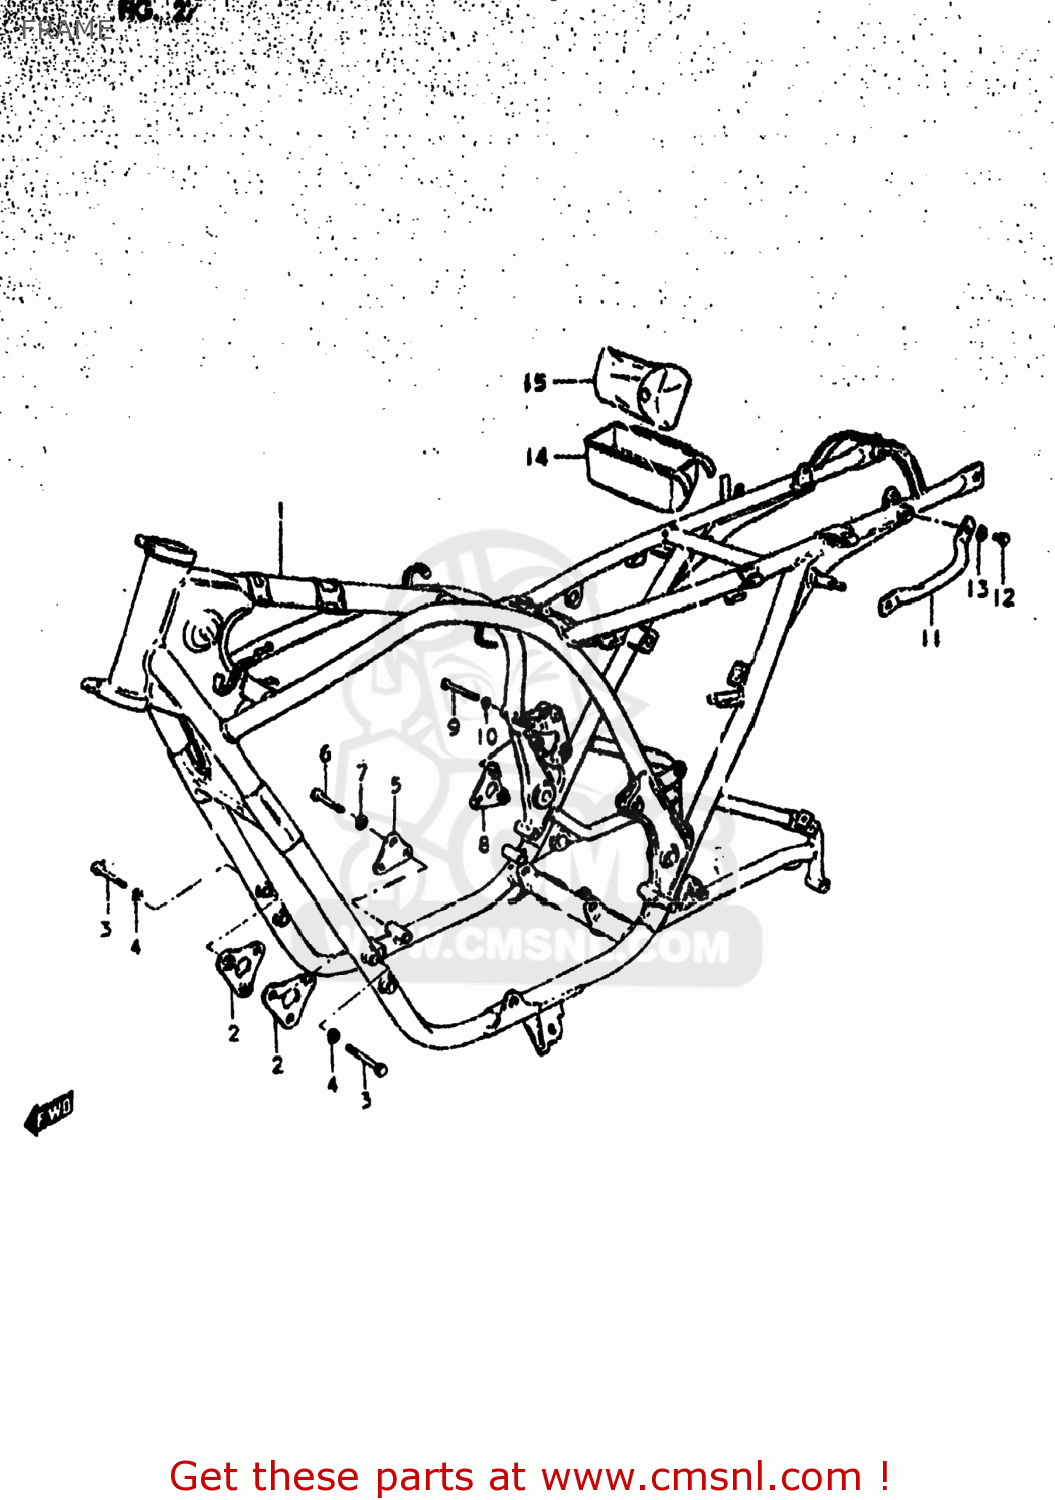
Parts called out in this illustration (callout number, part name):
1	FRAME
2	PLATE,ENGINE MOUNTING
3	BOLT
4	LOCK WASHER
5	PLATE,ENGINE MOUNTING
6	BOLT
7	LOCK WASHER
8	PLATE,ENGINE MOUNTING
9	BOLT 8X55
10	LOCK WASHER
11	GRIP,FRAME HANDLE
12	BOLT
13	WASHER
14	HOLDER,TOOL
15	TOOL SET
